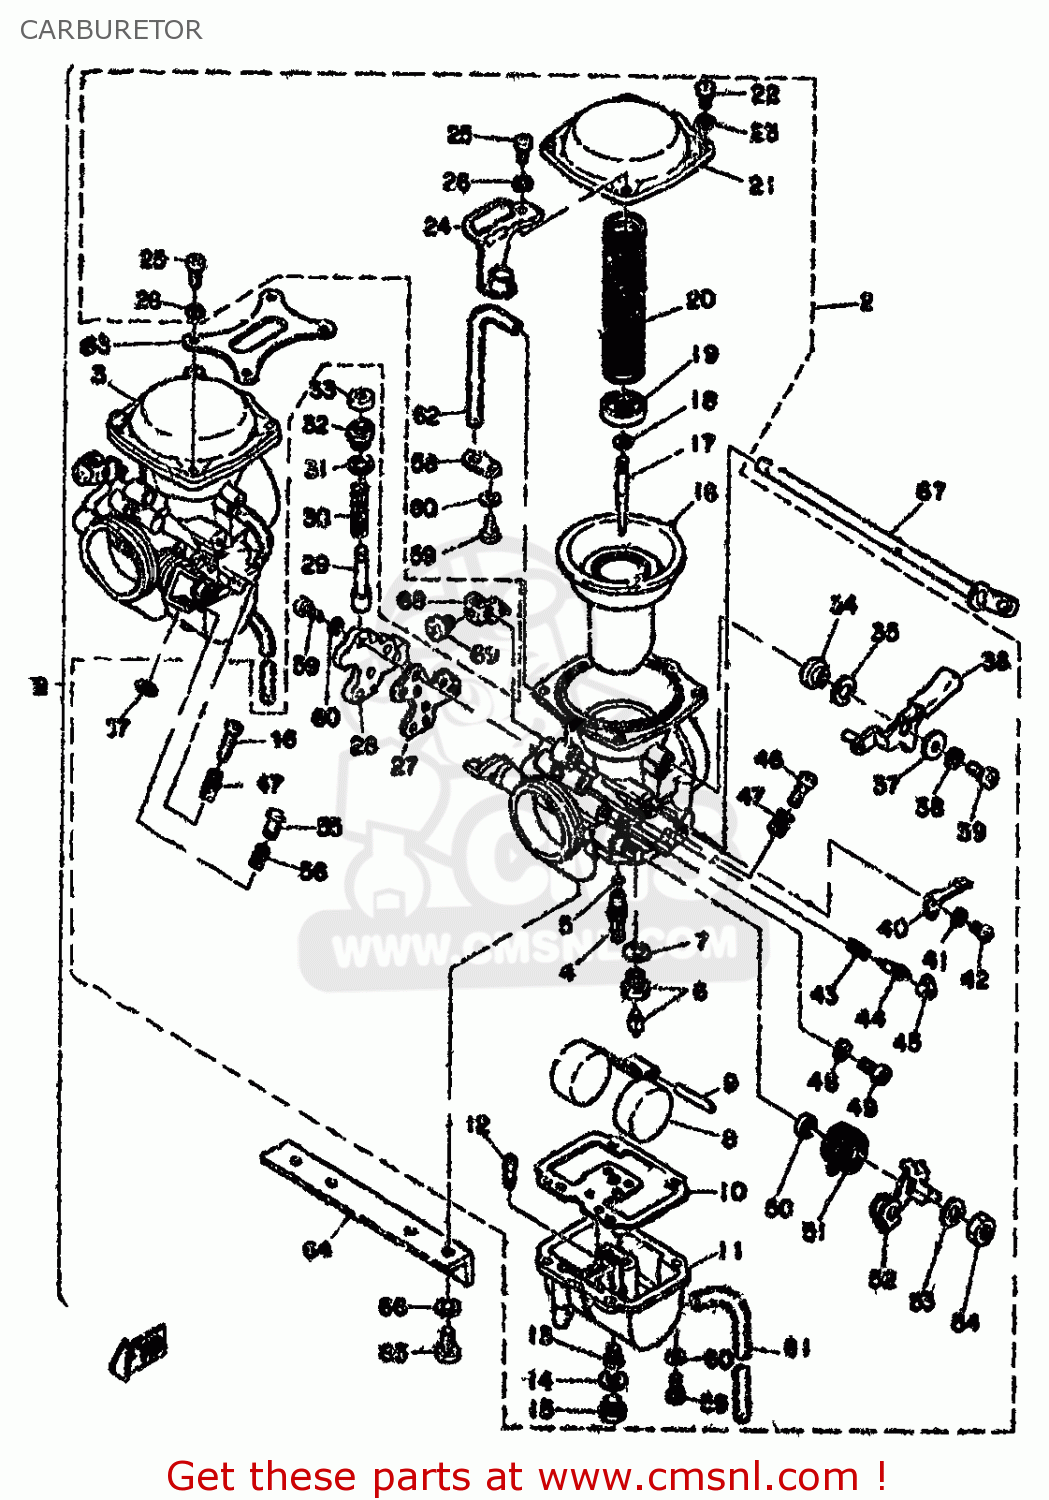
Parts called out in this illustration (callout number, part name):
1	CARBURETOR ASSEMBLY CANADA
2	CARBURETOR ASY 1
3	CARBURETOR ASY 2
4	NOZZLE, MAIN (Y-6)
5	O-RING (256)
6	VALVE SEAT ASSY
7	WASHER, VALVE SEAT
9	PIN, FLOAT
10	GASKET, FLOAT CHAMBER (MCA)
11	BODY, FLOAT CHAMBER
12	JET, PILOT (#30)
13	JET,MAIN (NO120)
14	WASHER
15	SCREW, PLUG
16	DIAPHRAGM ASSY
17	NEEDLE
18	CLIP
19	PLATE SET, NEEDLE
20	SPRING, DIAPHRAGM
21	COVER, DIAPHRAGM
22	SCREW, PAN HEAD
23	WASHER,SPRING
24	THROTTLE BRACKET ASSEMBLY
25	SCREW, PAN HEAD
26	WASHER,SPRING
27	GASKET, STARTER BODY (NAS)
28	BODY,STARTER 1
29	PLUNGER, STARTER
30	SPRING, PLUNGER
31	WASHER
32	CAP, PLUNGER
33	COVER, PLUNGER CAP
34	RING
35	WASHER, STARTER LEVER
36	LEVER ASSY
37	WASHER
38	WASHER, SPRING
39	SCREW,PAN HEAD
40	SPRING, STARTER LEVER
41	WASHER, SPRING
42	SCREW, PAN HEAD
43	SPRING, AIR ADJUSTING
44	SCREW, PILOT
45	CAP, PILOT SCREW
46	ADJUSTER, THROTTLE
47	SPRING, THROTTLE STOP
48	WASHER, PLUG SCREW
49	PLUG
50	SEAL
51	SPRING, THROTTLE (L.H)
52	LEVER,THROTTLE 2
53	WASHER, SPRING
54	NUT
55	ROD, PUSH
56	SPRING,THRTL STOP
57	CLIP
58	PLATE
59	SCREW,PAN HEAD
60	WASHER, SPRING
61	PIPE
62	HOSE
63	PLATE, UPPER
64	PLATE, LOWER
65	SCREW, PAN HEAD
66	WASHER, SPRING
67	SHAFT, STARTER LEVER
68	LEVER, STARTER 2
69	SCREW, STARTER LEVER 2
